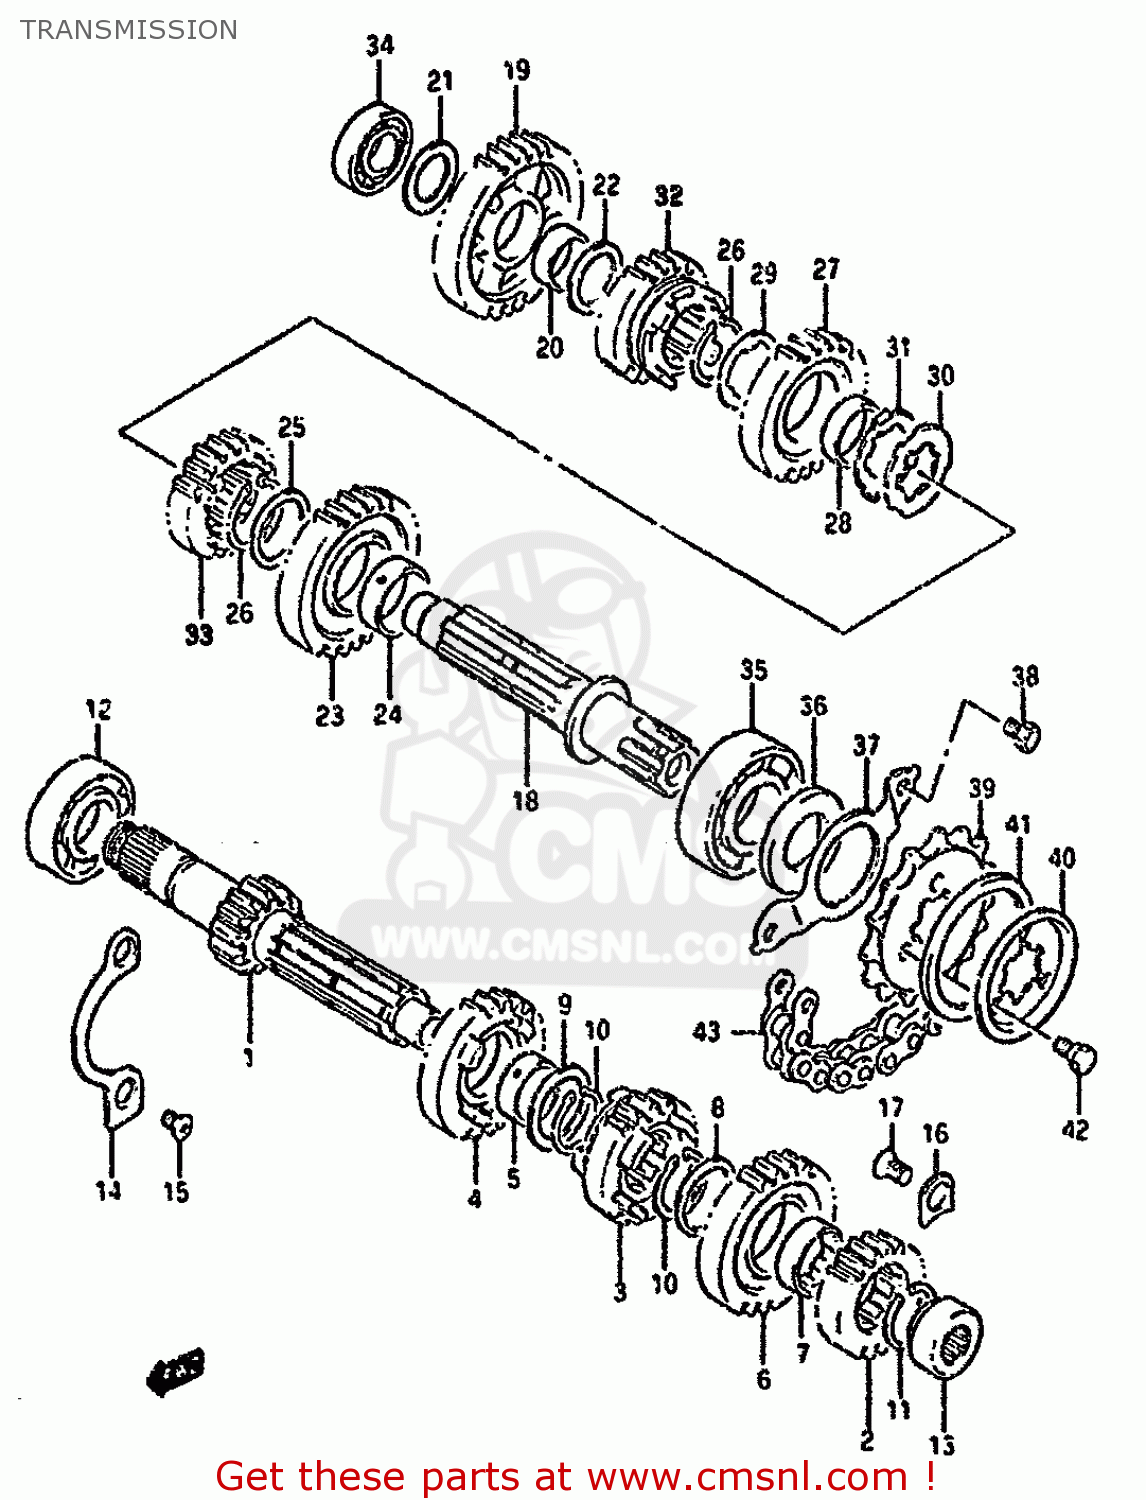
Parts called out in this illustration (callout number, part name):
1	SHAFT,COUNTER
2	GEAR ,2ND DRIV
3	GEAR,THIRD DRIVE (NT:20)
4	GEAR,4TH DRIVE(NT:23)
5	BUSHING 25X29X10
6	GEAR,FIFTH DRIVE (NT:25)
7	BUSHING
8	WASHER,LOCK
9	WASHER
10	RING,SNAP
11	CIRCLIP
12	BEARING(22X56X16)
13	BEARING(17X30X14)
14	RETAINER,CNTR SHAFT BEARING
15	SCREW
16	RETAINER
17	SCREW
18	SHAFT,DRIVE
19	GEAR,1ST DRIVEN(NT:32)
20	BUSHING
21	WASHER,THRUST
22	WASHER
23	GEAR,2ND DRIVE
24	BUSH(28X32X11)
25	WASHER
26	CIRCLIP
27	GEAR,THIRD DRIVEN (NT:24)
28	BUSH
29	WASHER,LOCK
30	WASHER,LOCK
31	WASHER
32	GEAR,FOURTH DRIVEN (NT:22)
33	GEAR,FIFTH DRIVEN (NT:20)
34	BEARING(20X42X12)
35	BEARING(25X62X17)
36	SEAL,OIL(25X45X5)
37	RETAINER,DRIVE SHAFT OIL SEAL
38	BOLT
39	SPROCKET,ENGINE(15T)
40	PLATE,ENGINE SPROCKET
41	DAMPER,ENGINE SPROCKET
42	BOLT(6X13)
43	CHAIN(DID520VL2,116L)
